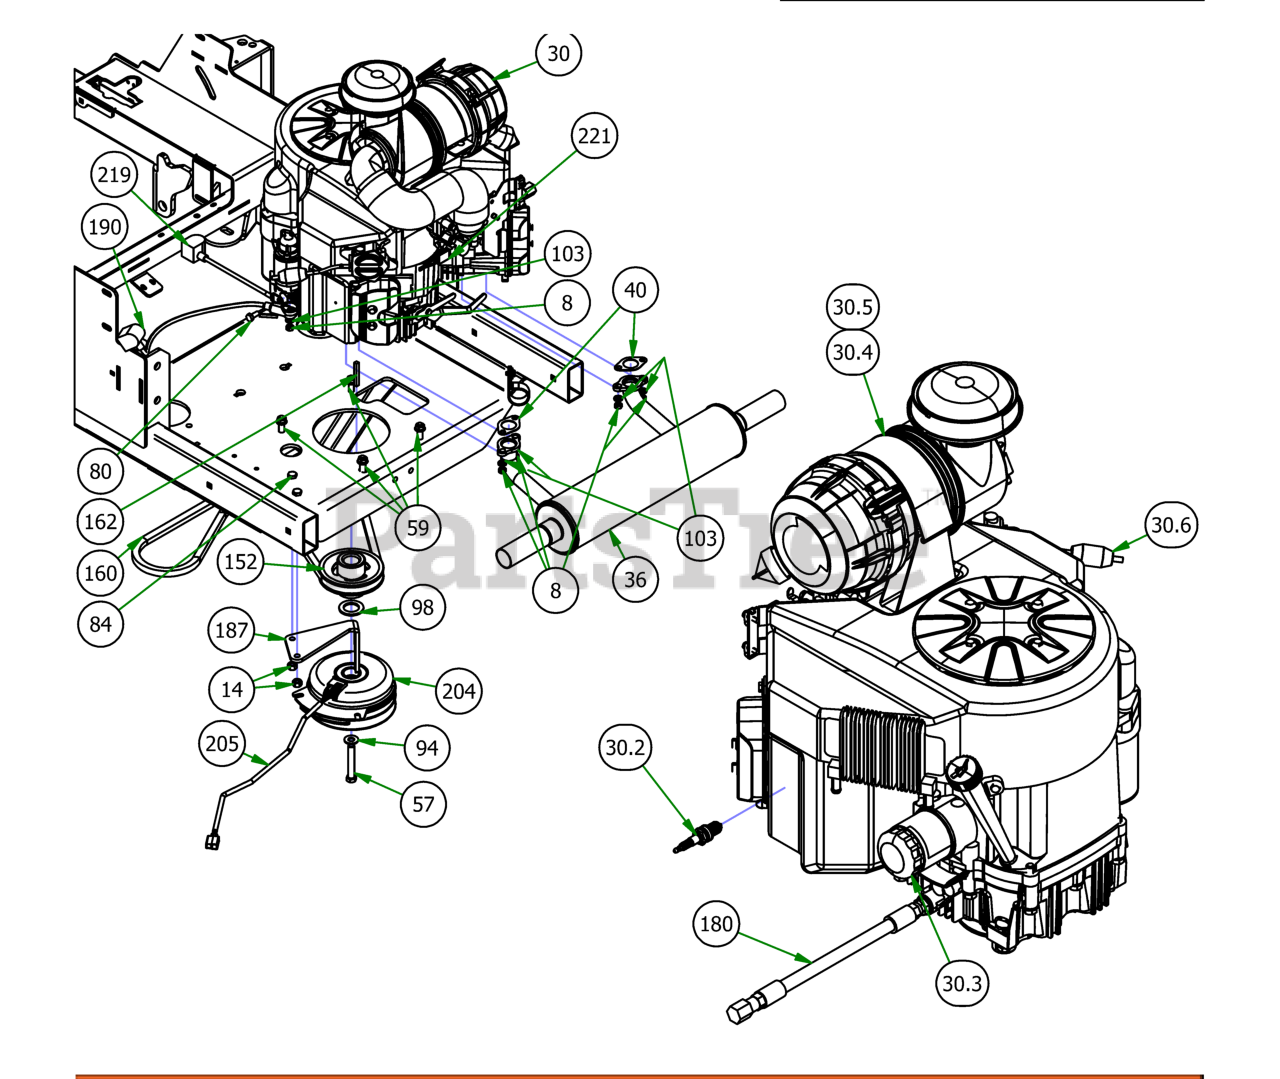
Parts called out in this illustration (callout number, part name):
8	M8-1.25 Zinc Nut
11	3/8-16 HEX SERRATED FLANGE NUT HARD/ZINC
14	3/8" Hex Nut
30	Kawasaki FX850 Engine
30.2	Spark Plug - Kawasaki
30.3	Oil Filter
30.4	Canister Air Filter- Inner
30.5	Canister Air Filter- Outer
30.6	Universal Inline Fuel Filter
36	2019 Rebel/Rogue Kawasaki 850 Muffler
40	Exhaust Gasket
49	M6-1.0 X 12MM DIN 933 HEX TAP BOLT (CL 8.8) ZINC
57	7/16-20 x 2 3/4 Hex C/S GR 8 Yellow Zinc
59	3/8 x 1 1/8 bolt
80	M8x1.20x20MM Hex head bolt
82	3/8 x 1 1/2 Bolt
84	3/8" x 1" Hex Bolt
94	3/8 FLAT WASHER USS (1" OD) ZINC
98	1 1/8" Flat Spacer
100	1/4 USS Flat Washer Zinc
103	5/16" Lock Washer
152	4 3/4 Motor Pulley
160	2019 Rogue Pump Belt 68"
162	1/4 x 2 Square key Stock
180	Kawasaki Oil Drain
187	PTO Engager Holder
190	24" Red Battery Cable
204	Clutch Assembly
205	Clutch Pigtail
206	2019 Veritical Suspension Frame
208	Diesel Hydraulic Hose Clamp
219	Starter Cable
221	Kawasaki Harness Adapter
